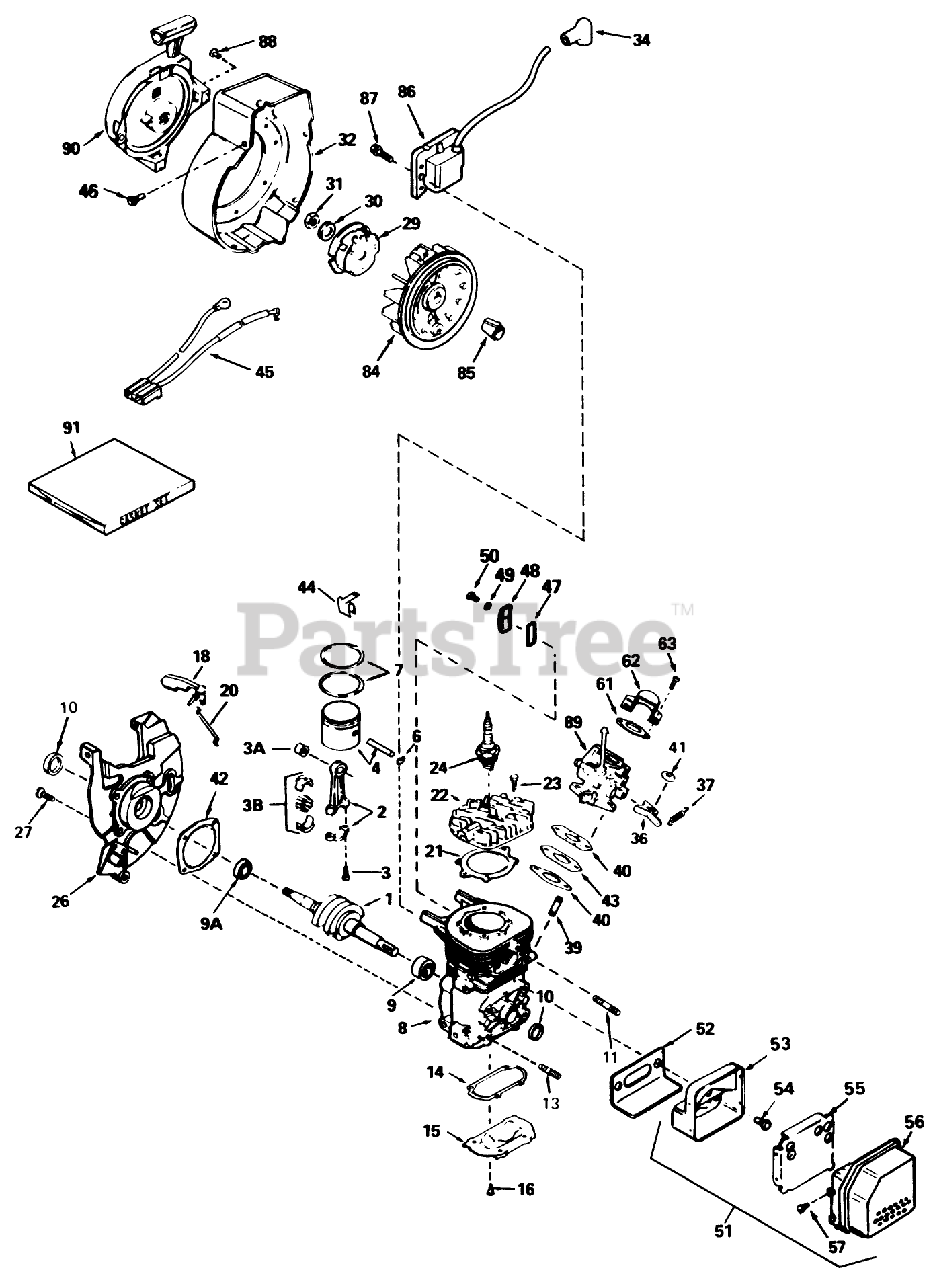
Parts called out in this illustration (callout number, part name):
1	Crankshaft
2	Rod Assy.-Connecting (Incl. Ref. #3, 3A 3B)
3	Bolt-Rod, Connecting
3A	Bearing-Cartridge
3B	Needle Bearing and Liner Set (37 Needles)
4	Piston (Incl. Ref. #43)
6	Ring-Retaning
7	Ring Set
8	Cylinder Block Assembly
9	Bearing-Cartridge
9A	Bearing-Ball
10	Seal-Oil
14	Cover
15	Plate-Cover
16	Screw (T-25, 10-24 x 1/2)
18	Vane-Air
20	Link-Governor
21	Gasket-Head, Cylinder
22	Head-Cylinder
23	Screw (T-30, 1/4-20 x 3/4)
24	Spark Plug-Resistor (R C J 8Y)
26	Base Assy.-Blower Housing (Incl. Ref. #10)
27	Screw (T-30, 1/4-20 x 5/8)
29	Cup-Starter
30	Washer-Belleville
31	Nut-Flywheel
32	Housing-Blower
34	Cover-Spark Plug
36	Lever-Adjusting, Rpm
37	Spring-Governor
40	Gasket-Carburetor
41	Locknut
42	Gasket-Cover, Cylinder
43	Spacer
44	Clip-Wire
45	Harness-Wire
46	Screw-Hex, Hd.
47	Cover-Compression, Release
48	Comp. Release Cover
49	Washer
50	Screw (T-25, 10-24 x 1/2)
51	Muffler Assembly (Incl. Ref. #53-57)
52	Gasket-Exhaust
53	Base-Muffler
54	Screw (T-30, 1/4-20 x 5/8)
55	Baffle-Muffler
56	Cover Muffler
57	Screw
61	Gasket
62	Baffle-Carburetor
63	Screw
84	Flywheel
85	Blade (20 inch)
86	Solid State
87	Screw
88	Rivet-Pop
89	Carburetor (Incl. Ref. #184A)
90	Starter-Rewind
91	Gasket Set
